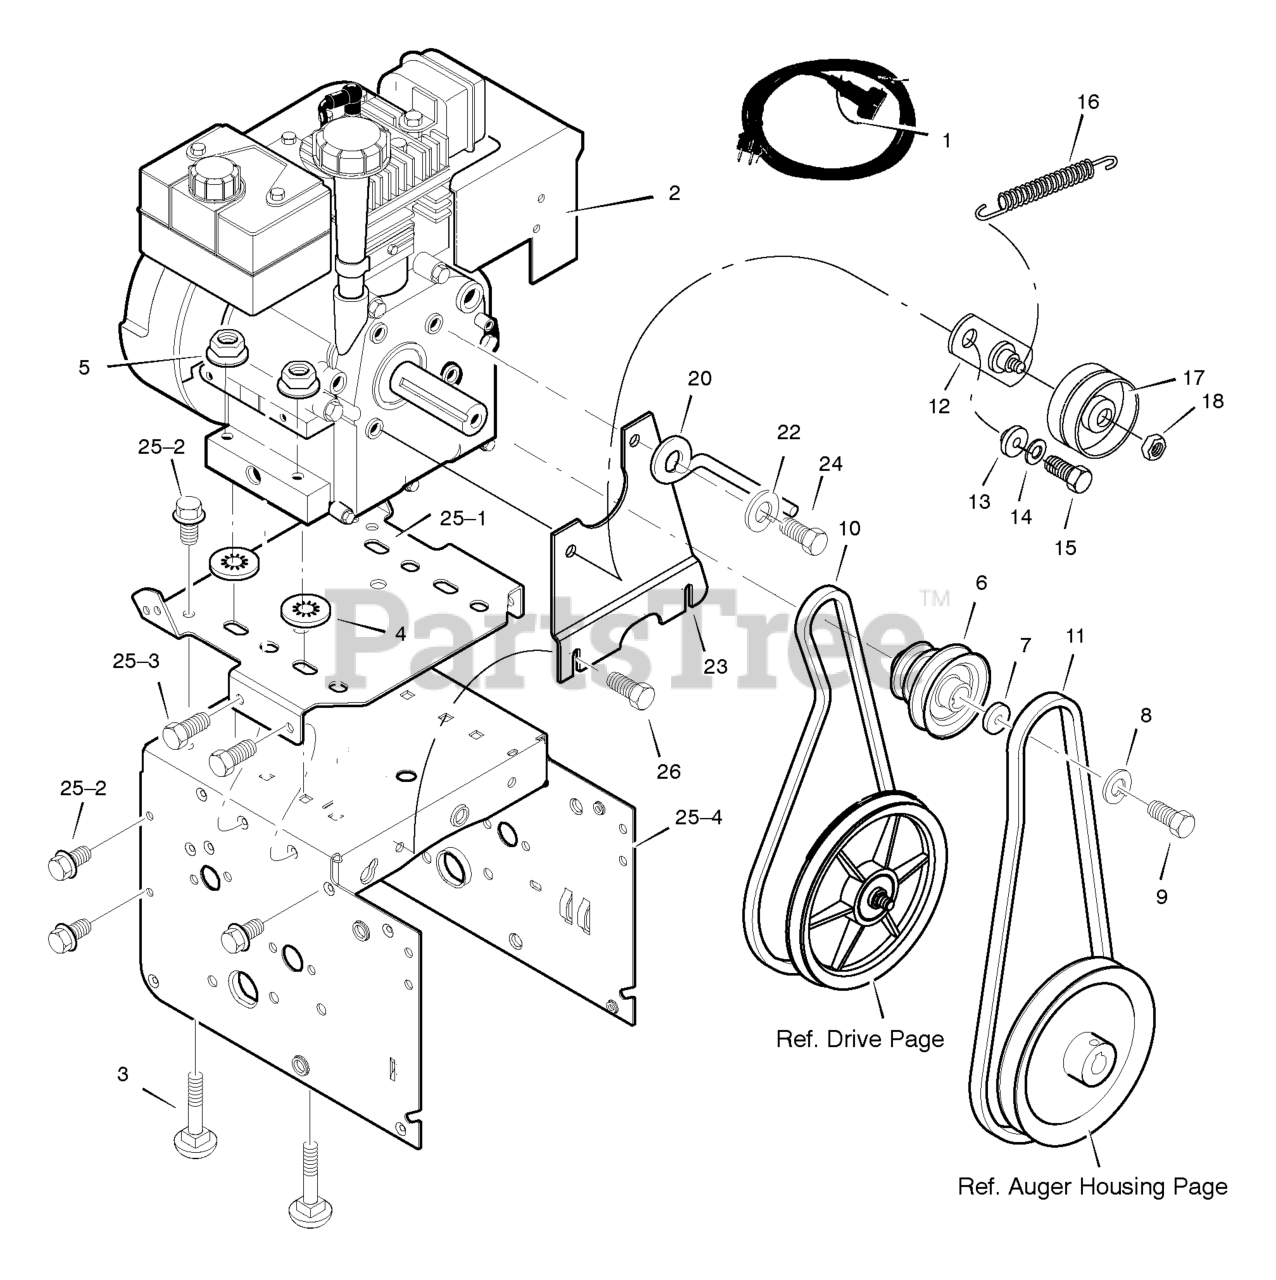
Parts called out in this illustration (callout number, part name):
1	CORD, Electric, 10FT. 110V
2	Engine *
3	BOLT, CARRIAGE 5/16-18
4	RETAINER, PUSH
5	NUT, HEX 5/16-18
6	PULLEY, ENGINE
7	WASHER
8	WASHER .38ID
9	SCREW, 3/8-24 x 1.00
10	BELT, DRIVE V 3L
11	BELT, AUGER V 4L
12	BRACKET ASSEMBLY, IDLER
13	BUSHING, IDLER BRACKET
14	WASHER, SPLIT
15	SCREW 5/16-24 X 1.00
16	SPRING, IDLER TRACTION DRIVE
17	PULLEY, IDLER
18	NUT, JAM 3/8-16
20	GUIDE, BELT
22	WASHER, SPTLK .31X.58X.08
23	PLATE, ANTI VIBRATION
24	SCREW, 5/16-24 x 1.00
25	FRAME ASSEMBLY
25-1	PLATE, ENGINE MOUNT
25-2	SCREW, TAP 1/4-20 X .63
25-3	SCREW, TAP 5/16-18 X .50
25-4	FRAME, MOTOR BOX
